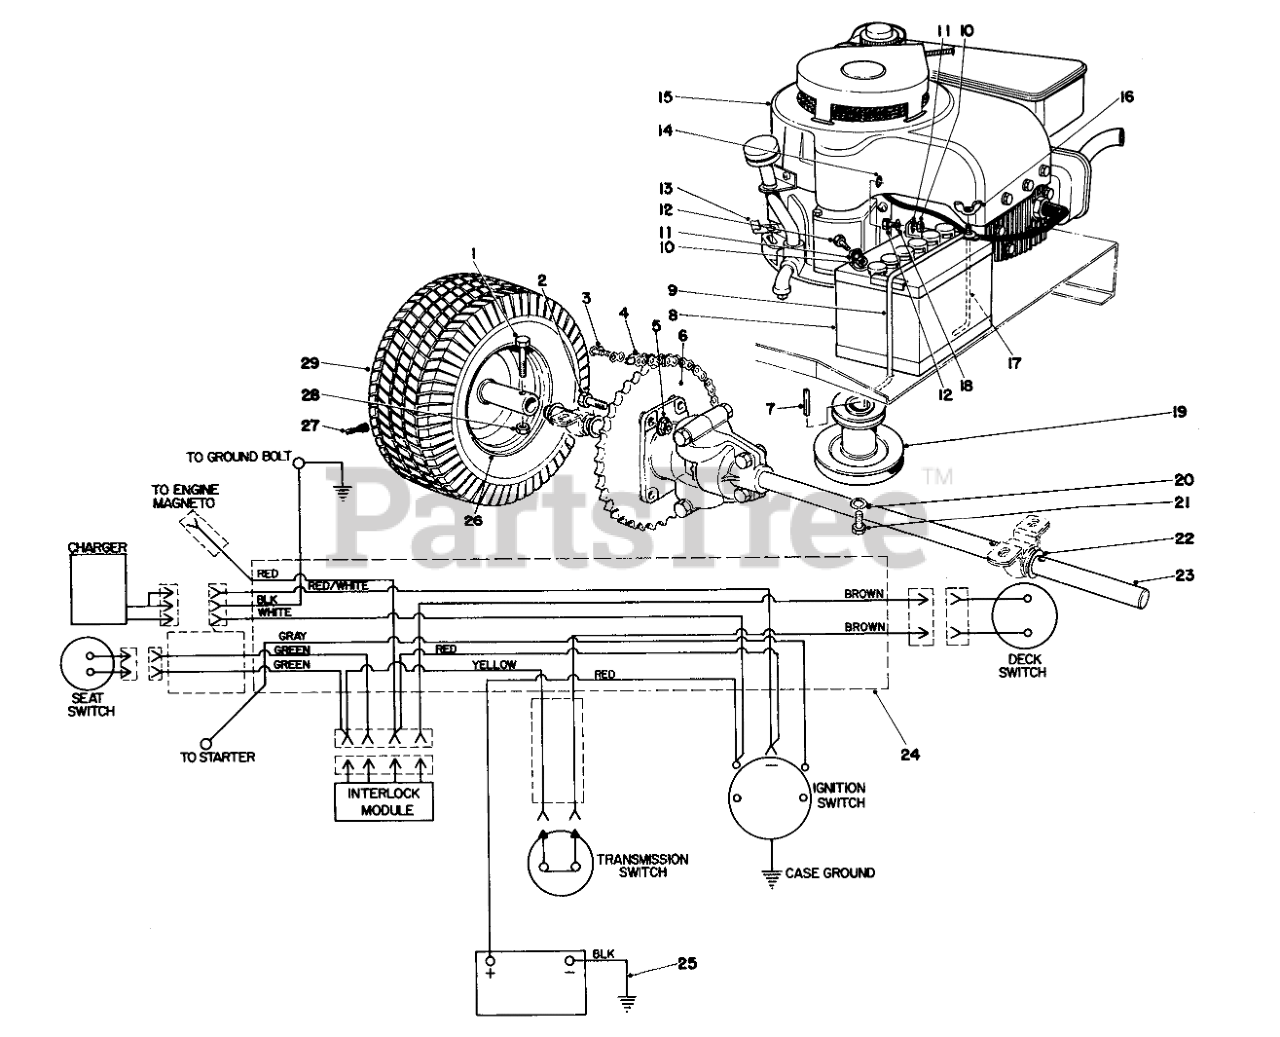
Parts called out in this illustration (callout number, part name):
1	SCREW-HH
2	SCREW-HH
3	LINK-CONNECTING
4	Chain Roller (Incl. Ref. #3)
5	NUT-LOCK, CONE
6	Sprocket
8	BATTERY
9	Battery Clamp
10	NUT-HEX
11	WASHER-LOCK
12	Bolt
14	WASHER-LOCK/EXT
15	Engine
16	NUT-WING SPECL
17	ROD-SUPPORT, BATTERY
18	WASHER-FLAT
19	Engine Pulley
20	WASHER-LOCK
21	SCREW-HH
22	WASHER
23	Differential
24	Wiring Harness
25	ENG-GROUND WIRE ASM
27	STEM-VALVE
28	NUT-LOCK, CONE
29	Tire
